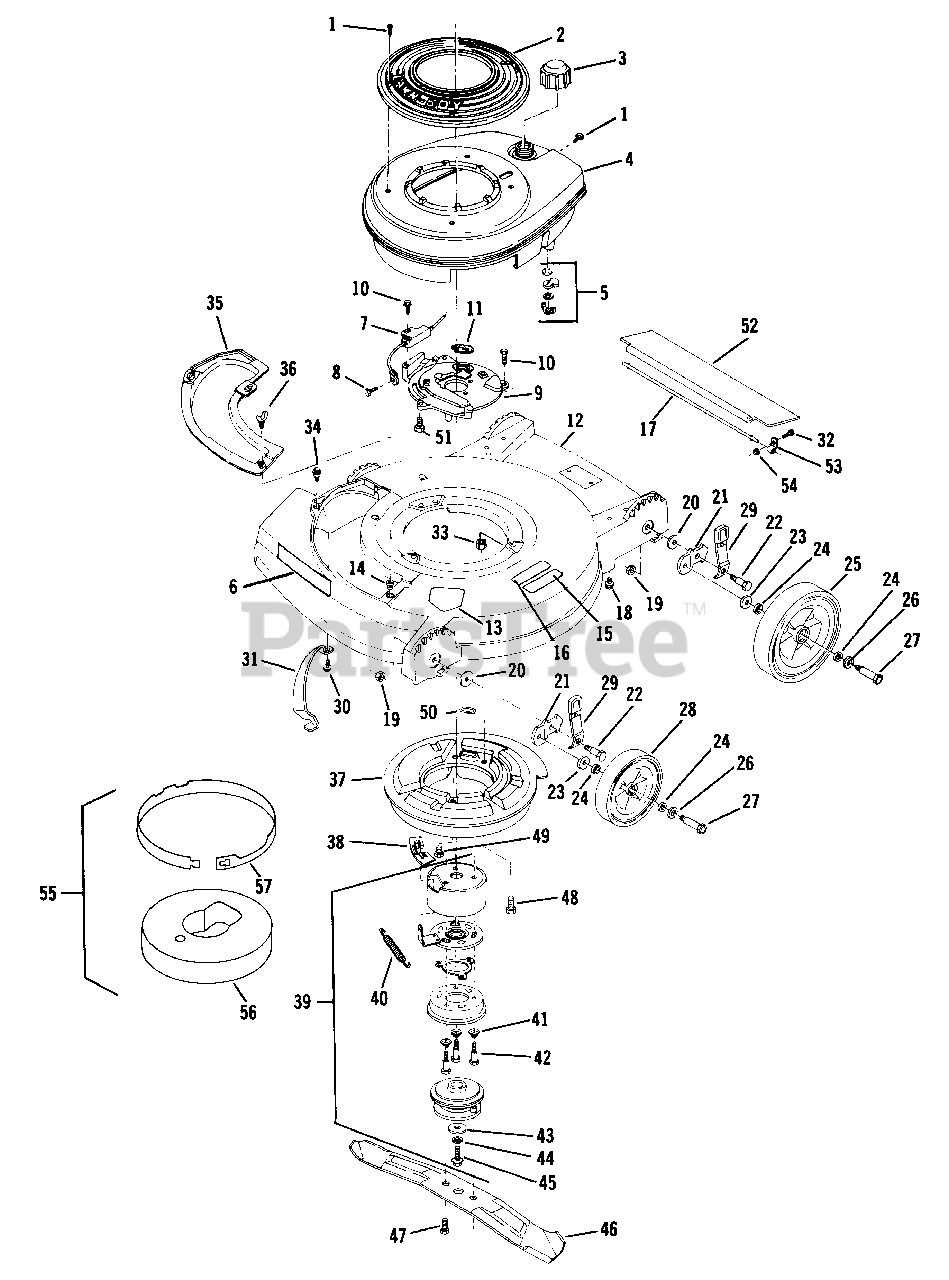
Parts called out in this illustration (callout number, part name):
1	Screw
2	Cover-Shroud
3	Fuel Cap
4	Shroud
5	Fuel Shut-Off Assembly
6	Decal-Clutch
7	Control Cable Assembly
8	Bolt-Shoulder
9	Plate-Engine Mtg.
10	Screw-Eng. Mtg. Plate and Cable Assembly to Housing
11	Gasket-Exhaust
12	Housing-Assembly
13	Decal-Blade Contact Warning
14	Grommet
15	Starting Pad
16	Decal-Starting Pad
17	Rod-Trailing Shield
18	Screw-Handle Brkt. to Housing
21	Bracket-Whl. Hgt. Adj.
22	Bolt-Shoulder
24	Washer-Felt
25	Wheel-Rear
27	Bolt-Wheel
28	Wheel-Front
29	Knob and Spring Assembly
30	Screw
31	Toe Bar
32	Screw
33	Nut-Eng. Mtg. Plt. to Hsg.
34	Screw-Plate and Chute Mtg.
35	Cover-Chute
36	Wing Screw
37	Muffler Assembly
38	Shield-Actuator
39	Clutch Brake Assembly
41	Spring Pressure
42	Screw-Shoulder
44	Lockwasher
45	Screw-Socket Head
46	Blade-21"
47	Screw-Sems-Blade
48	Screw-Muff. to Block
49	Screw-Muffler to Engine Mounting Plate
50	Seal-Exhaust
51	Screw-Engine Mounting Plate to Block
52	Shield-Trailing
55	Muffler Seal and Shield Kit
56	Seal-Muffler
57	Shield-Muffler Seal
